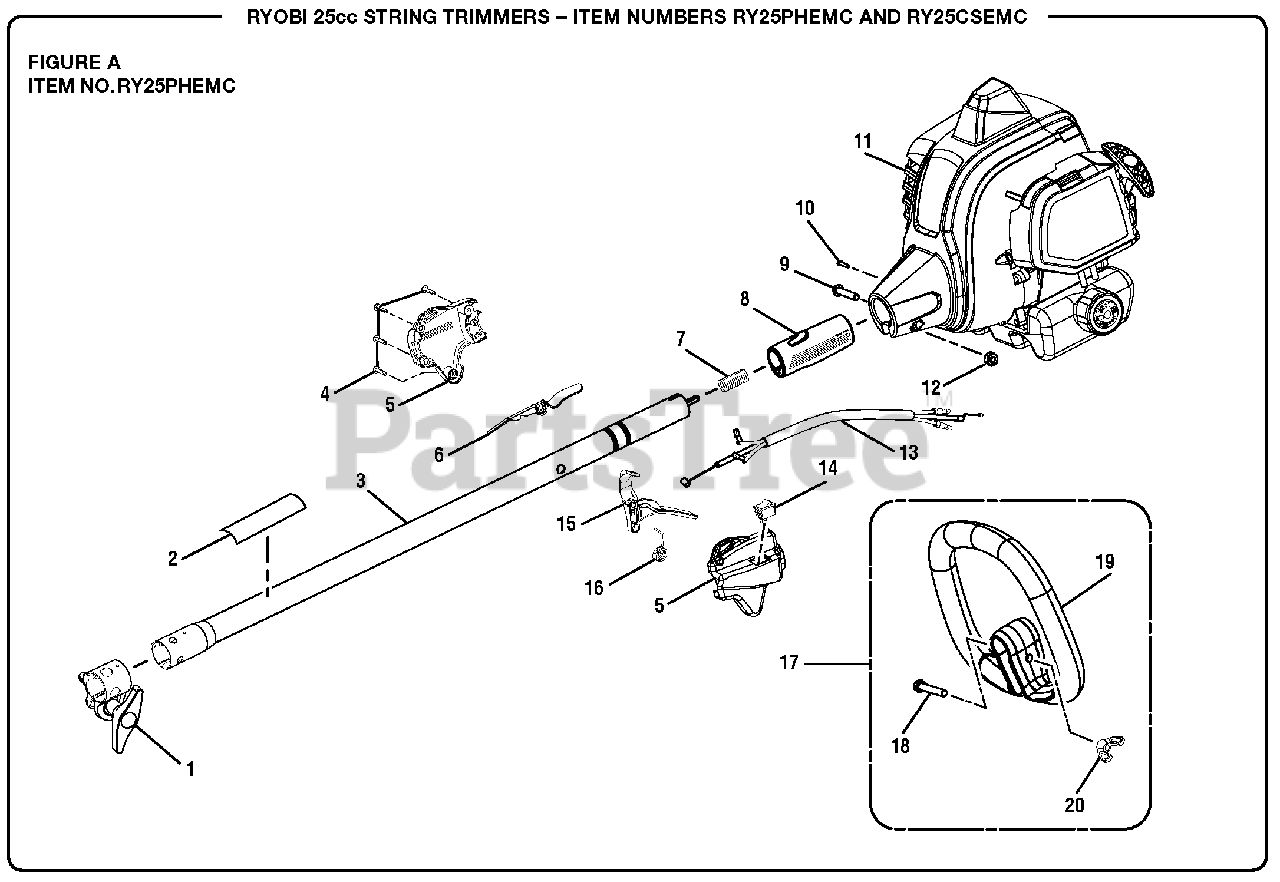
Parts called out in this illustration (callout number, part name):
1	Boom Clamp Assembly
2	Warning Icon Label
3	Upper Boom Assembly
4	Screw (M4 x 20 mm, T20 Torx Hd. S.T.)
5	Control Handle Assembly
6	Trigger Lock
7	Compression Spring
8	Rear Handle Grip
9	Screw (M6 x 30 mm, T27 Torx Button Hd.)
10	Screw (M4 x 8 mm, T20 Torx Pan Hd. S.T.)
11	Powerhead Assembly w/Labels
12	Hex Nut (M6 x 1)
13	Throttle Cable and Wire Assembly
14	On/Stop Switch
16	Trigger Spring
17	Front Handle Assembly
18	Screw (1/4-20 x 40 mm, Cap Hex Hd.)
19	Front Handle
20	Wing Nut (1/4-20)
